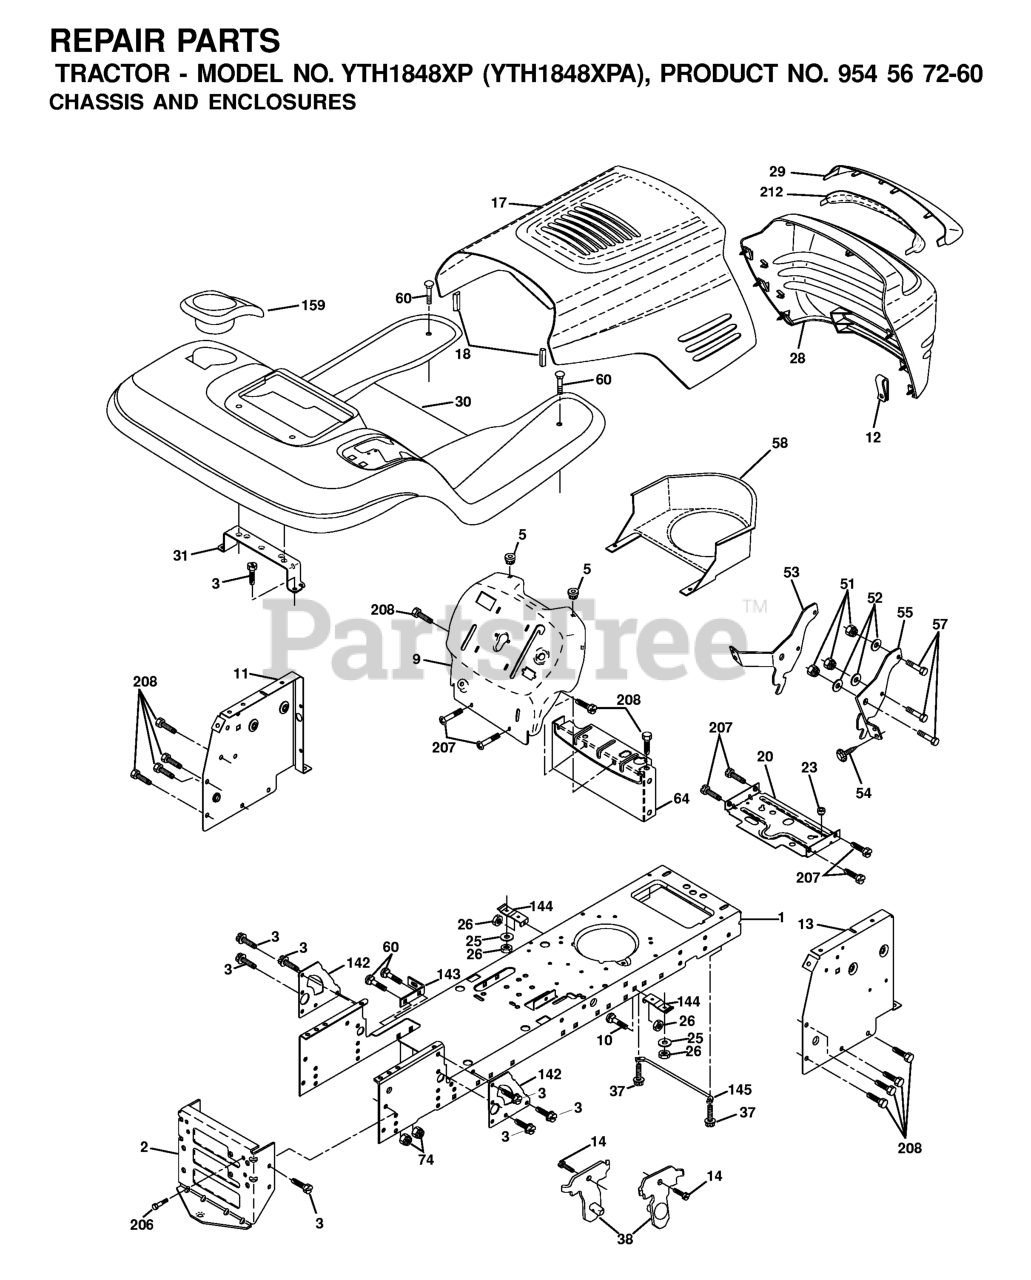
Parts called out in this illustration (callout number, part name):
1	CHASSIS STAMPING
2	DRAWBAR, 12GA
3	SCREW 3/8-16X3/4
5	BUMPER.RUBBER.HOOD
9	DASH SLKSCR
10	BOLT D
11	PANEL DASH LH
13	PANEL ASM, DASH RH
17	HOOD ASM.
18	BUMPER HOOD T
20	PLATE MTG
23	BUSHING.SNAP.NYL.BLK.
25	WASHER
26	NUT
28	GRILLE ASM
29	LENS
31	BRACKET.SUPPORT.FENDER
37	Screw 5/16-18 x 1/2 Hex, Self Tapping 5/16-18 x 1/2
38	BRACKET.ASM.PIVOT.MOWER.REAR
51	LOCKNUT.NYLOC.1/4-20
53	BRACKET.GRILLE.LH
54	SCREW.HEX.WS.HD.8-18 X 7/8
57	BOLT
58	AIR CONDUCTOR
60	Bolt - Rd. Hd. Sq. Neckiage 3/8 16 x 3/4
64	DASH LOWER
142	PLATE
143	BRACKET, SWAY BAR
144	BRKT, FOOT REST
145	ROD PIVOT CHASSIS/HOOD
159	CUPHOLDER
206	SHOULDER BOLT 5/16-18TT
207	SCREW, 5/16-18 X 1/2
208	SCREW 3/8-16X1/2
212	REPL BY 532 1745-03
